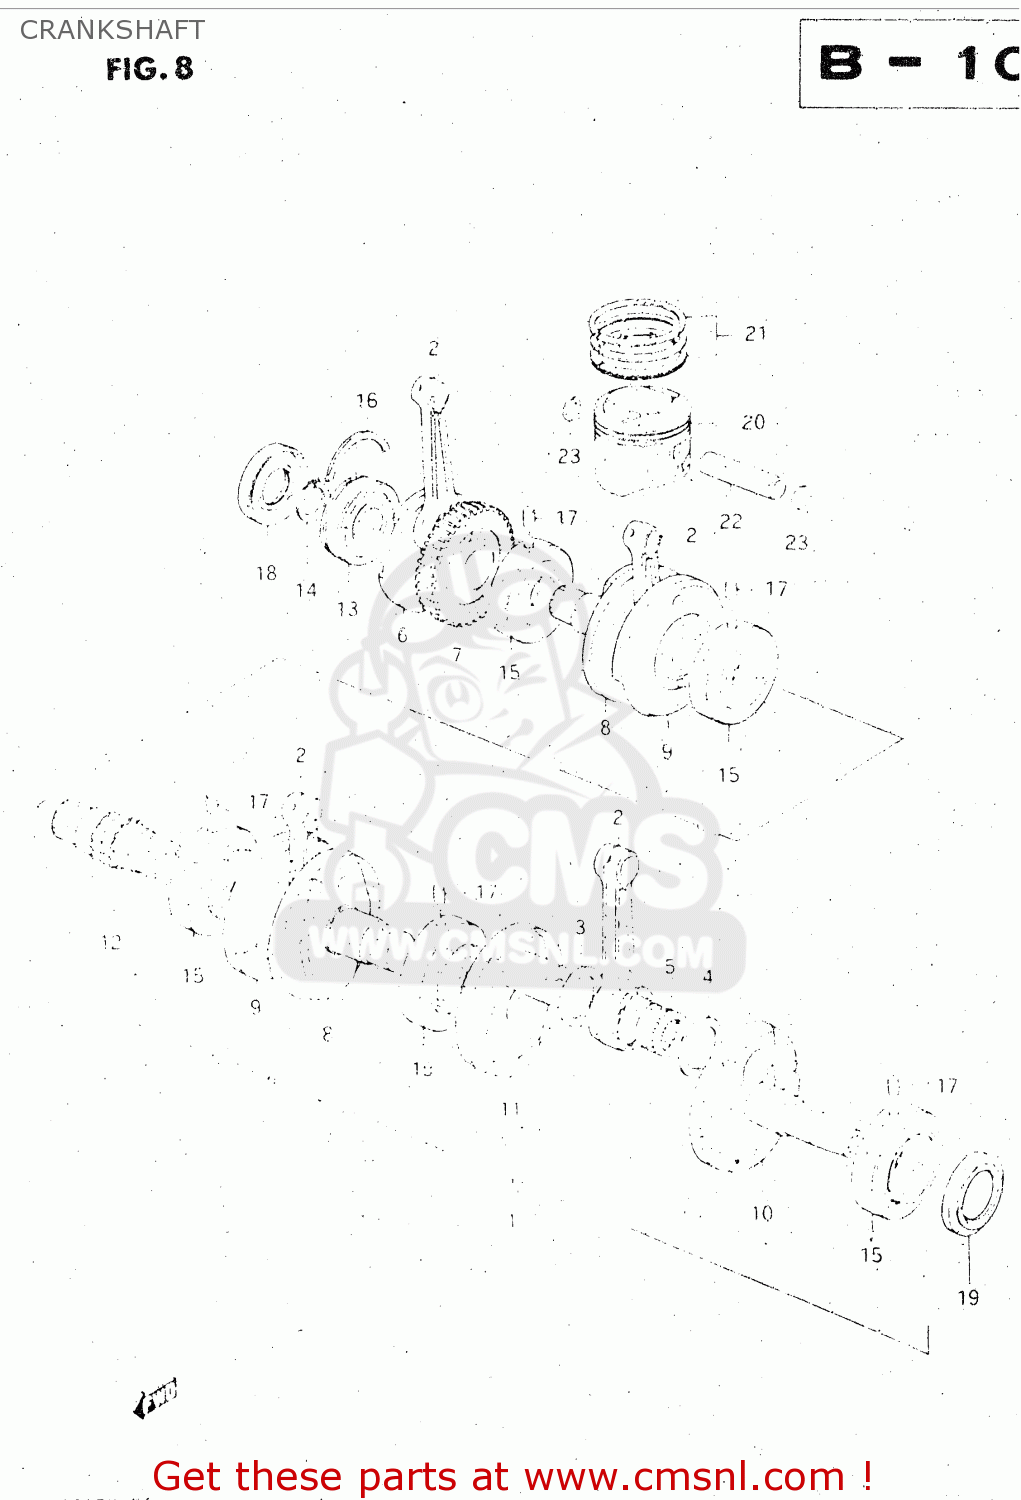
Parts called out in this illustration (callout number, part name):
1	CRANKSHAFT ASSEMBLY
2	ROD,CONNECTING
3	WASHER (28X48X2)
4	WASHER(28X48X1)
5	ROLLER BEARING (28X38X16.8)
6	CRANKSHAFT
7	WEB,CRANK
8	CRANKSHAFT
9	WEB,CRANK,MIDDLE
10	CRANKSHAFT,LEFT
11	WEB,CRANK,LEFT
12	SHAFT,TIMING CHAIN DRIVE
13	BEARING(30X72X19)
14	CIRCLIP,30MM
15	BEARING
16	C RING
17	PIN
18	SEAL,OIL(30X72X11)
19	OIL SEAL, STARTER CLUTCH GEAR
20	PISTON
21	PISTON RING SET (STD)
22	PIN,PISTON 16MM
23	CIRCLIP
